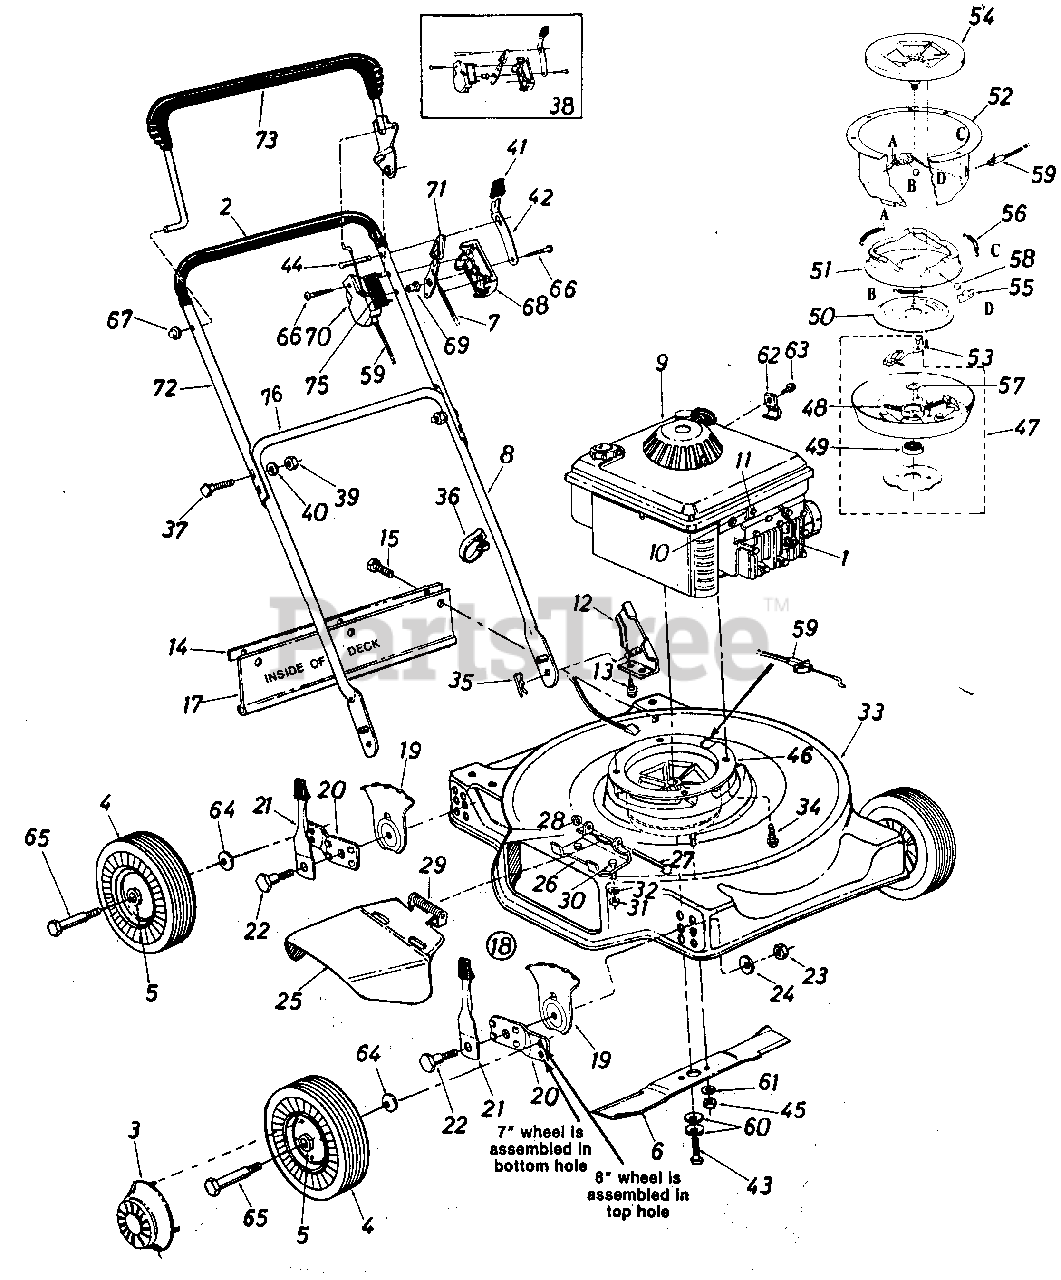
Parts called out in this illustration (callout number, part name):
1	Spark Plug Boot
2	Grip Optional Parts
3	Hub Cap
4	Wheel Ass'y. Comp.
5	Bearing
6	20" Blade
7	Throttle Control Wire-53"
8	Lower Handle (Chrome)
9	Engine
10	Casing Clamp
11	Hex Sems Scr. #10-32 x .62" Lg.
12	Handle Mount Brkt. Ass'y.-L. H.
13	Hex Wash. Hd. B-Tap Scr. 5/16-1 8 x .50" Lg.
14	Retaining Strip
15	Hex Wash. Hd. AB-Tap Scr. 1/4" x .62" Lg.
17	Rear Flap Ass'y.
18	Height Adj. Ass'y.-R.H. Optional Parts
19	Height Adj. Plate Optional Parts
20	Pivot Bar
21	Spring Lever w/Knob
22	Shld. Bolt .500" Dia. x 375
23	Hex ut 3/8-16 Thd.*
24	Bell-Wash. .39" I.D. x 1.13" O.D.
25	Chute Def lector Ass'y. Comp.
26	Deflector Hinge Plate
27	Pivot Pin
28	Cap Speed Nut 1/4" Rod
29	Torsion Spring
30	Hex Bolt 1/4-20 x .50" Lg.*
31	Hex Nut 1/4-20 Thd.*
32	L-Wash. 1/4" I.D.*
33	20" Deck Ass'y.
34	Hex Wash. Hd. TT-Tap Scr. 3/8-16 x 1.00" Lg.
35	Intern. Cot. Pin 5/16" Dia.
36	Cable Tie
37	Curved Carriage Bolt 5/16-18 x 1.38" Lg.
38	Kit-Control Housing Comp.
39	Hex Nut 5/16-18 Thd.*
40	L-Wash. 5/16" I.D*
41	Spring Lever Knob
42	Lock Out Spring
43	Hex Cent. L- Bolt 3/8-24 x 2.00" Lg.
44	Lock Pin .75" Dia. x 1.80
45	Special Hex Nut 5/16-24 Thd.
46	Blade Brake Clutch Ass'y.-Comp.
47	Clutch Blade Housing Ass'y.
48	Comp. Spring .35" O.D. x 2.00" Lg.
49	Ball Brg. .669" I.D. x 1.574"
50	Clutching Cone
51	Brake Cup Cone
52	Clutch Housing
53	Hex Wash. TT-Tap Cl.-Scr. 1/4-20 x .75" Lg.
54	Fan Adapter
55	Ball Block
56	Extension Spring .35" O.D. x 1.75" Lg.
57	Fl-Wash. .690" I.D. x 1.060" O.D.
58	Steel Ball .500" Dia.
59	Clutch Cable-42"
60	Bell-Wash. .400" I.D. x .88"O.D.
61	L-Wash. 3/8" I.D.
62	Casing Clamp
63	Hex B-Tap Scr. 10 x .38" Lg.
64	Bell-Wash. .400" I.D. x .88" O.D.
65	Axle Bolt
66	Truss Mach. Hi-B Tap Scr. #12 x 1.50" Lg.
67	Cap Speed Nut 5/16" Rod
68	Control Panel Half
69	Control Disc Pin
70	Clutch Panel Half
71	Throttle Control Lever
72	Upper Handle (Chrome)
73	Control Handle Ass'y.
75	Control Label-Throttle
76	Instruction Label-Handle
